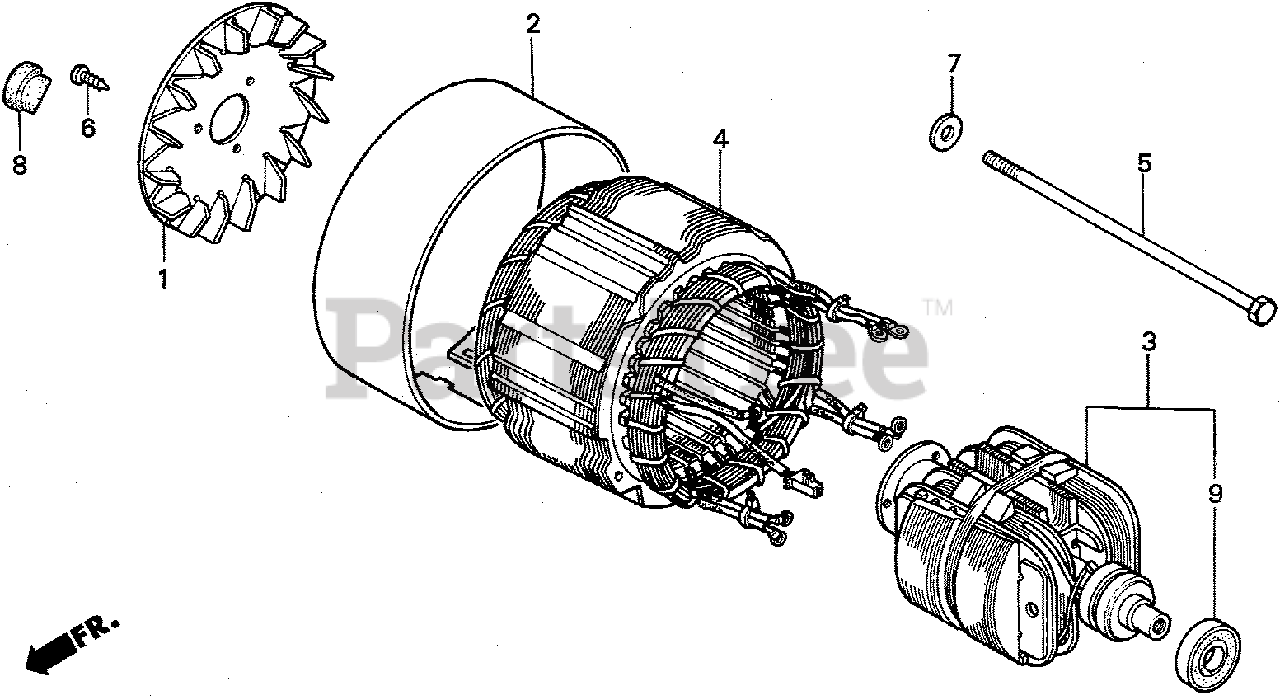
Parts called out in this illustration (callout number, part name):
1	FAN, GENERATOR COOLING
2	COVER, STATOR
4	STATOR ASSY. (120V/4KVA)
5	BOLT, HEX. (10X283)
6	SCREW, TAPPING (5X14)
7	WASHER (10.5MM)
8	GROMMET, CRANKCASE
9	BEARING, RADIAL BALL (6205UU)
